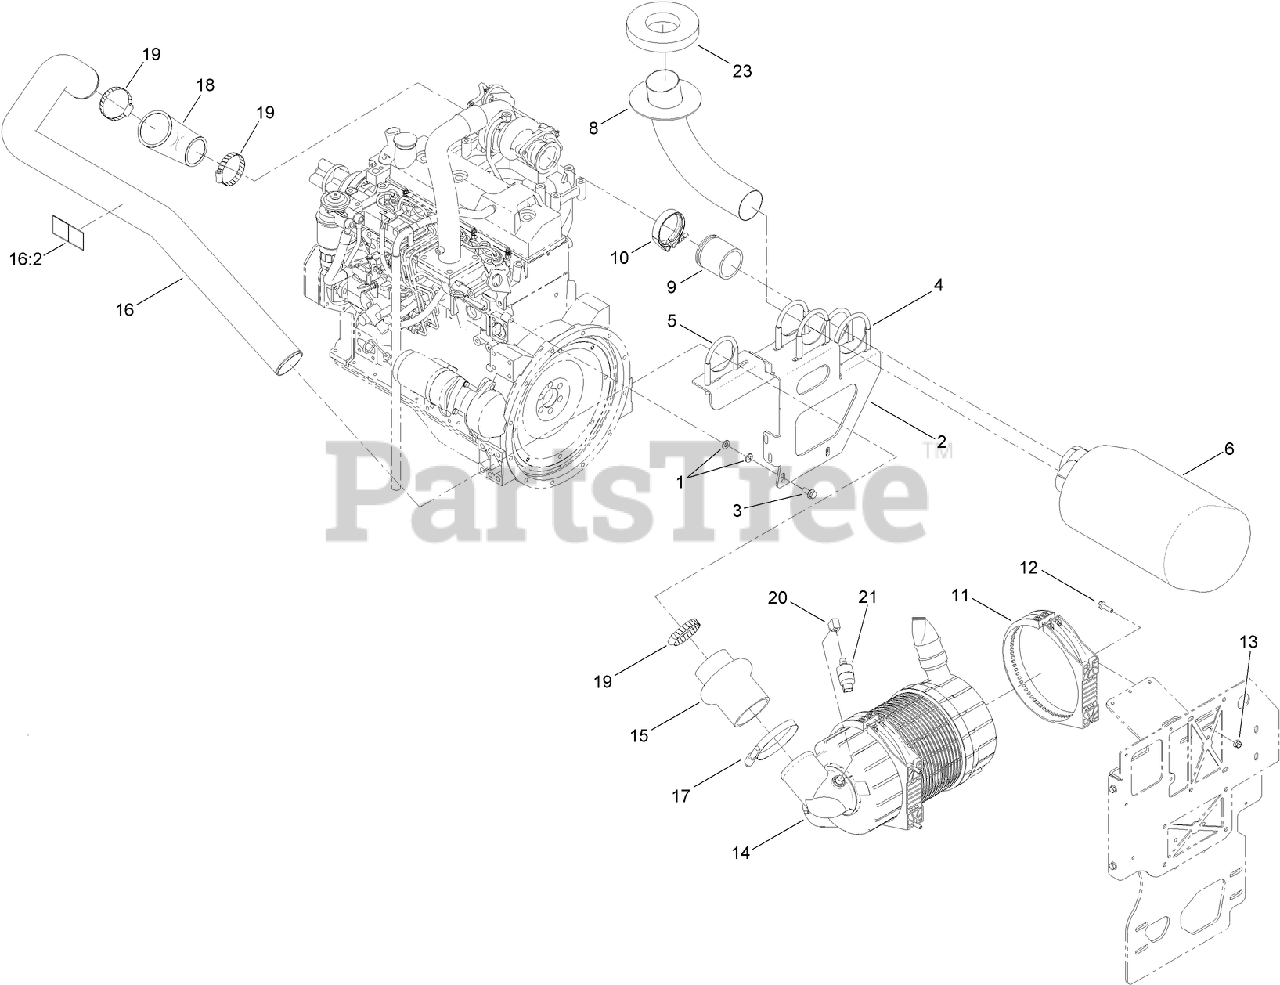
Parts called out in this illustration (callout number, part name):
1	WASHER-FLAT
2	BRACKET-MOUNT, MUFFLER
3	SCREW-HHF
4	CLAMP-GUILLOTINE
5	CLAMP-GUILLOTINE
6	MUFFLER
8	TUBE-EXHAUST (W/ SEAL PLATE)
9	FLANGE-ADAPTER, TURBO
11	BAND-MOUNTING, AIR CLEANER
12	SCREW-HHF
13	NUT-LOCK, HHF
14	AIR CLEANER ASM
15	REDUCER-HOSE
16	AIR INTAKE ASM
16:2	DECAL-WARNING, HOT SURFACE
17	CLAMP-TORQUE, CONSTANT
18	ELBOW-90 DEG
19	CLAMP-HOSE
20	FITTING-ELBOW, 90
21	SWITCH ASM
23	INSULATION
